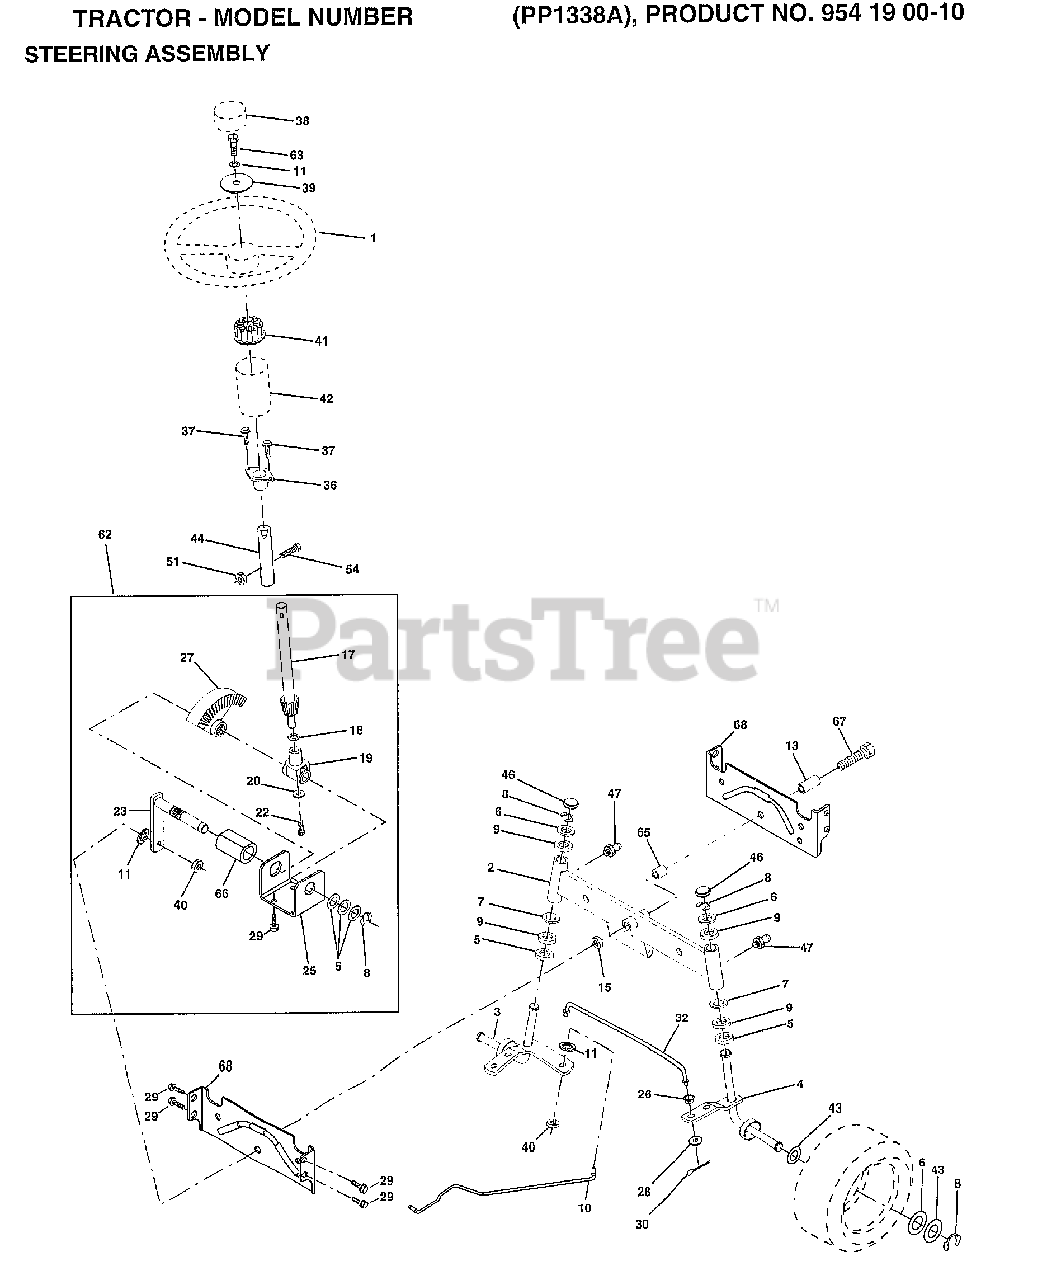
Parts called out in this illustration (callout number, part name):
2	AXLE ASM
3	SPINDLE.ASM.LH
4	"SPINDLE ASM,RH"
5	WASHER .T
6	WASHER
7	WASHER
8	RING
9	COL. SRTG. BEAR.
10	DRAGLINK-STAMPED
11	LOCKWASHER
13	BEARING AXLE
15	"NUT-LOC,FLANGE LT"
17	SHAFT ASM STEERIN
18	THRUST WASHER
19	SUPPORT.SHAFT
22	SCREW HEX SOC1/4-
25	BRKT-STEERING
26	BUSHING.DRAGLINK
27	GEAR SECTOR
28	WASHER
29	SCREW
30	COTTER PIN
32	TIE ROD
36	BUSHING.STEERING
37	"SCREW-TT,10-32 FL"
38	"INSERT,STR WHEEL"
39	WASHER T
40	GRIPCO NUT
41	ADAPTER LT
42	BOOT.STEER.PL
43	WASHER
44	EXT SHAFT STEERIN
46	CAP
47	ZERK M
51	NUT
54	BOLT
62	KIT STEERING ASM
63	BOLT
65	SPACER AXLE
66	"BEARING-ARM,PITMA"
67	BOLT
68	BRACE AXLE
